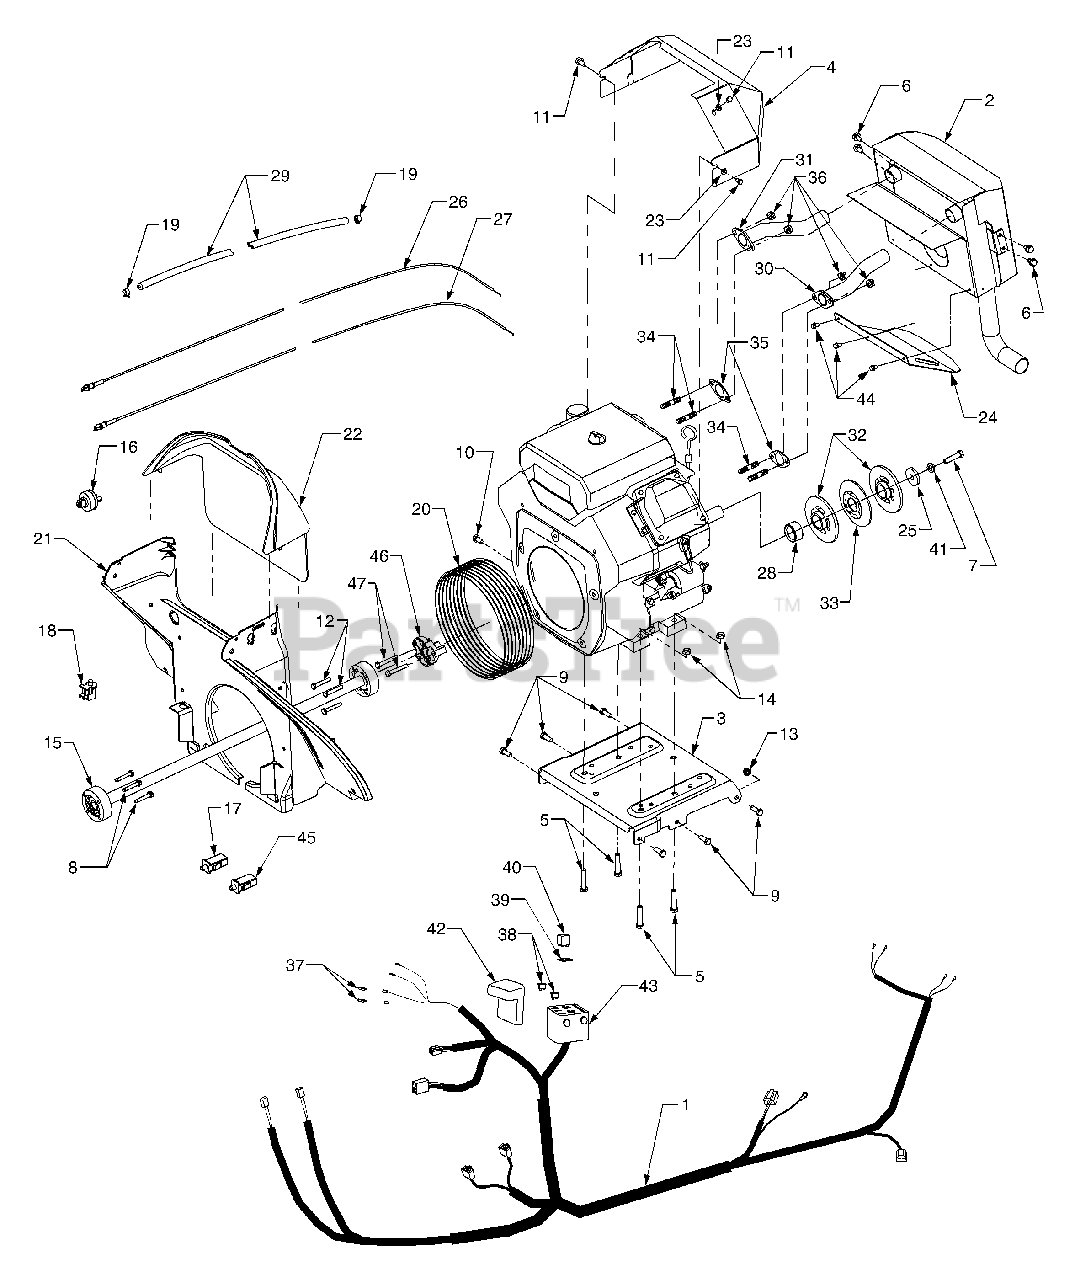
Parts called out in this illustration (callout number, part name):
1	Harness, Wire
1	Tie, Pushmount
1	Clip, Cable
2	Muffler Assembly
3	Plate, Engine Mounting
4	Shield, Muffler Heat
5	Screw, Hex Cap, 3/8-24 x 1.75 GR5
6	Screw, Hex Wash. Hd. Tapp 5/16-18 x .5
7	Screw, Hex Cap, 7/16-20 x 1.5 GR5
8	Screw, Hex Cap Lock 1/4-20 x 1.25 GR5
9	Screw, Hex Cap, 5/16-18 x .875 GR5
10	Screw, Hex Cap, M8 - 1.25 x 16MM GR5
11	Screw, Hex Cap, M6 - 1.0 x 10MM
12	Screw, Hex Cap, Lock 1/4-20 x 1.62 GR5
13	Nut, Hex Insert Lock, 5/16-18
14	Nut, Hex Lock, 3/8-24
15	Shaft, Drive, 27.125 Long
16	Switch, Key, w/Groung
17	Switch, Plunger
18	Switch, Snap Mount
19	Clamp, Hose
20	Boot, Intake
21	Baffle, Lower Air
22	Baffle, Upper Air
23	Washer, Flat, .281 x .50 x .06
24	Shield, Lower Exhaust
25	Washer, Flat, .417 x 1.5 x .225
26	Cable, Throttle Control
27	Cable, Choke Control
28	Spacer, Crankshaft
29	Hose, Fuel Line (60" Lg.)
30	Pipe, Exhaust RH
31	Pipe, Exhaust LH
32	Pulley Half
33	Pulley, Center
34	Stud, M8 - 1.25 x 33MM
35	Gasket, Exhaust
36	Nut, Hex, M8 x 1.25
37	Bulb, Indicator
38	Fuse, 25 Amp
39	Gasket, Silicone
40	Relay
41	Washer, Lock, 7/16
42	Cover, Fuse Box
43	Box, Fuse
44	Screw, Hex Wash. Hd. Tapp, #12-24 x .38
45	Switch, Plunger
46	Adapter, Drive Shaft
47	Screw, Hex Flange, M10 x 1.5 x 90
